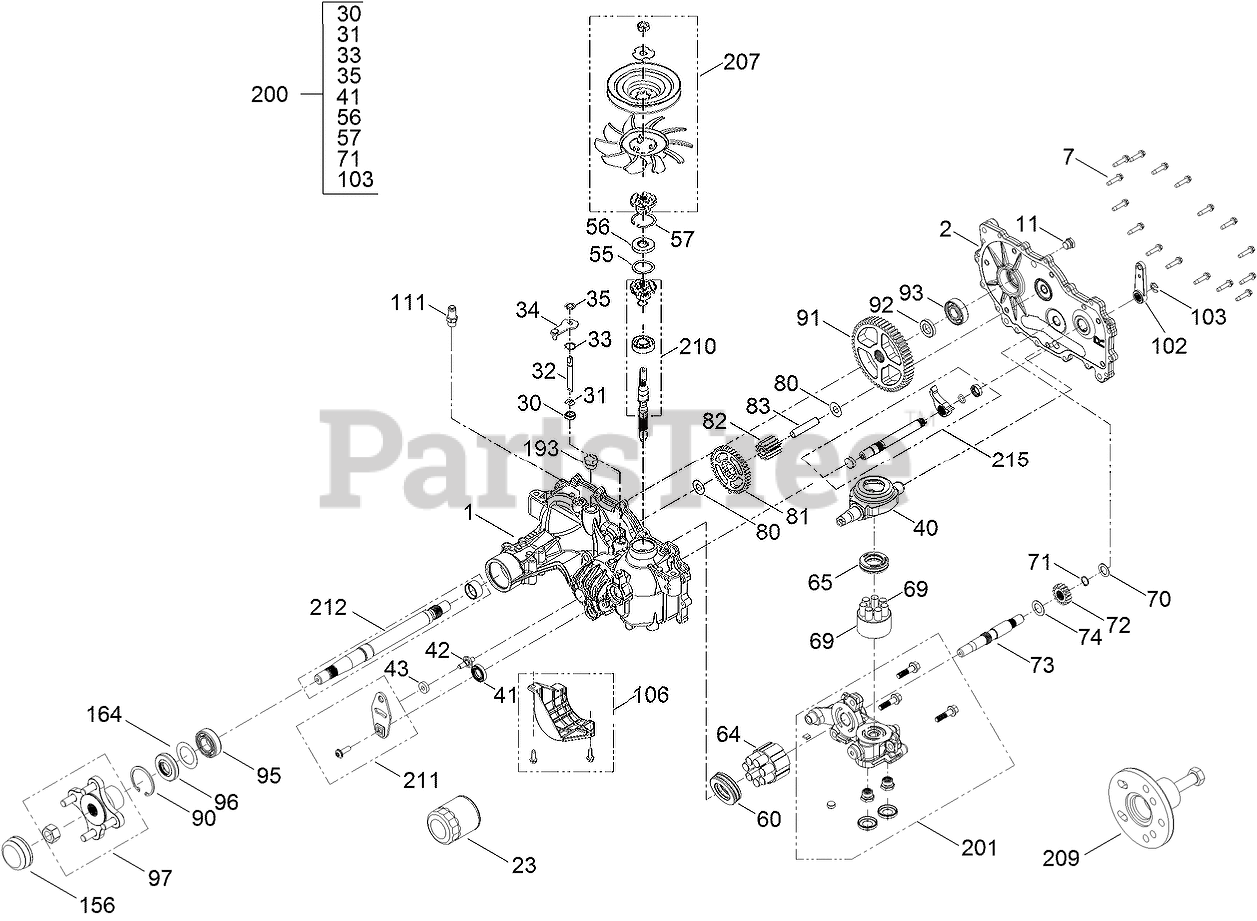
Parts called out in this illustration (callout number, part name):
1	KIT-HOUSING MAIN RH, CNTL
2	RH SIDE COVER KIT
7	SCREW-HHF
23	ELEMENT-OIL FILTER, HYD
30	SEAL-LIP
31	RING-RETAINING, EXTERNAL
32	ROD-BYPASS
33	RING-RETAINING, INTERNAL
35	RING-RETAINING, EXTERNAL
40	SWASHPLATE-TRUNNION
41	SEAL-LIP
43	PUCK-FRICTION
55	SPACER
56	SEAL-LIP
57	RING-RETAINING
60	BEARING-THRUST
64	CYLINDER BLOCK ASM KIT
65	BEARING-THRUST
69	PUMP BLOCK ASM
70	WASHER-FLAT
71	RING-RETAINING
72	GEAR-16T
73	SHAFT-MOTOR
74	WASHER
80	WASHER
81	GEAR-43T
82	GEAR-11T
83	PIN-JACKSHAFT
90	RING-RETAINING
91	GEAR-54T
92	SPACER
93	BEARING KIT
95	BEARING-BALL
97	HUB KIT
102	HANDLE-BRAKE
103	RING-RETAINING, EXT
106	FILTER GUARD KIT
111	ADAPTER-STRAIGHT
156	COVER-NUT, AXLE
164	SPACER
200	SEAL KIT
201	RH CENTER SECTION KIT
207	FAN AND PULLEY KIT
210	KIT-INPUT SHAFT
211	CONTROL ARM KIT
212	AXLE SHAFT KIT
215	INBOARD KIT
